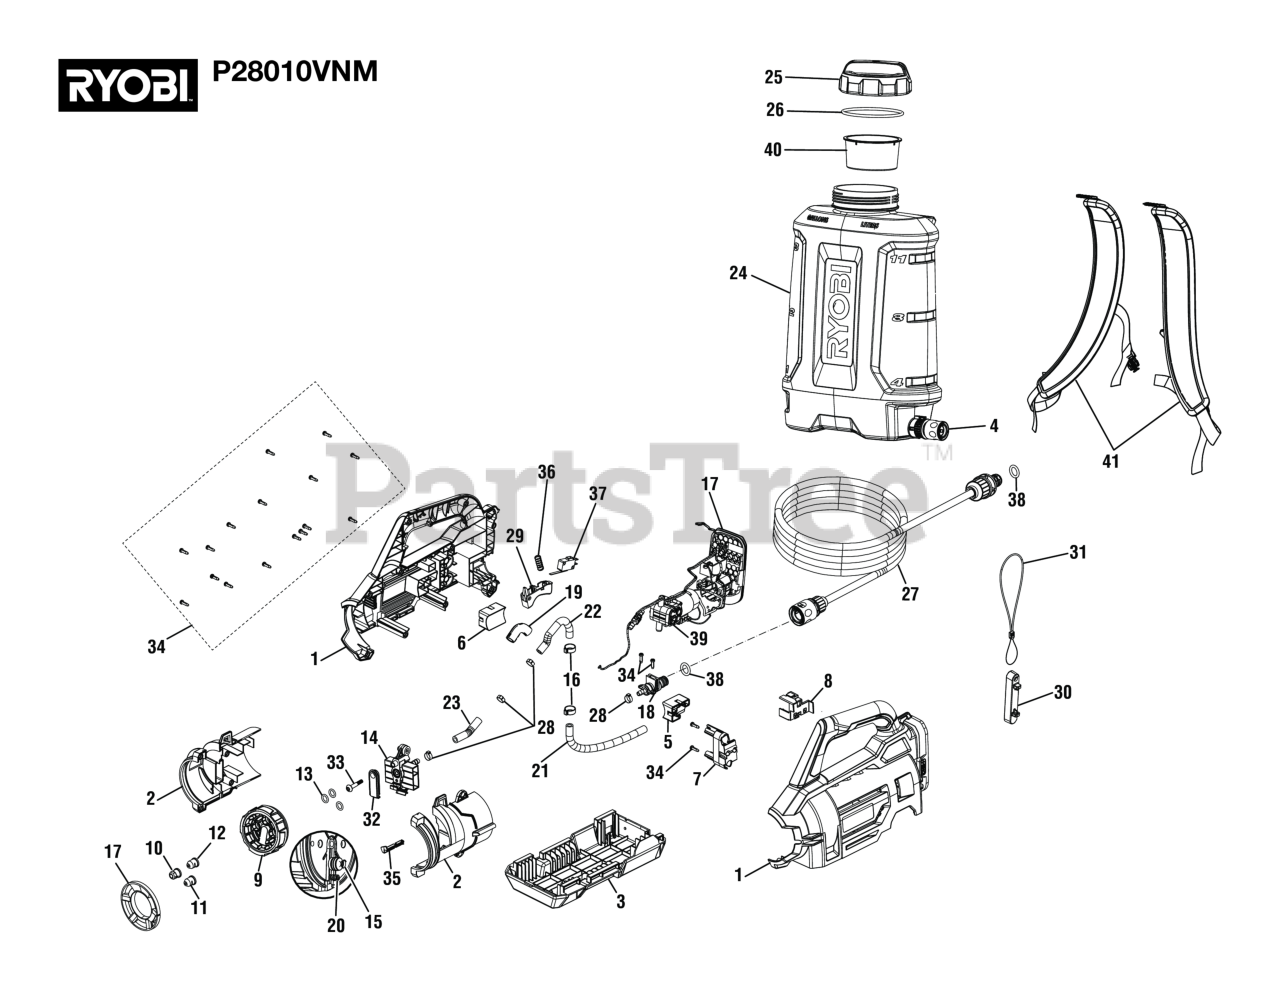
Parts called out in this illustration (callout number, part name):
1	Housing Assembly (Inc. Labels)
2	Outlet Tube Assembly (Inc. Label)
3	Bottom Plate Assembly (Inc. Label)
4	Shut-off Valve
5	Left Motor Support
6	Right Motor Support
7	Base for Pump
9	Nozzle Dial Assembly (Inc. Labels)
10	Low Spray Nozzle Assembly
11	Medium Spray Nozzle Assembly
12	High Spray Nozzle Assembly
14	Nozzle Body Assembly
15	Piston Seal Assembly
17	Motor & Battery Foot Assembly (Inc. Key Nos. 37, 39 & Labels)
18	Male Quick Connect
19	Pipe Shroud Assembly
20	Ball and Spring Assembly
21	Tube (Pump Inlet)
22	Tube (Pump Outlet)
23	Tube (Barb Nozzle)
24	Tank Assembly (Inc. Key Nos. 4, 25-26 & 40-41)
25	Tank Cap Assembly
27	Hose Assembly
29	Switch Trigger
30	Nozzle Wrench
32	Wheel Hub
33	Screw (M5)
34	Screw (M4 x 14 mm, T15 Torx Pan Hd.))
35	Wire Cover
36	Compression Spring
38	O-Ring (ID11.3 x CS2.5)
39	Motor & Pump Assembly
40	Inlet Filter
